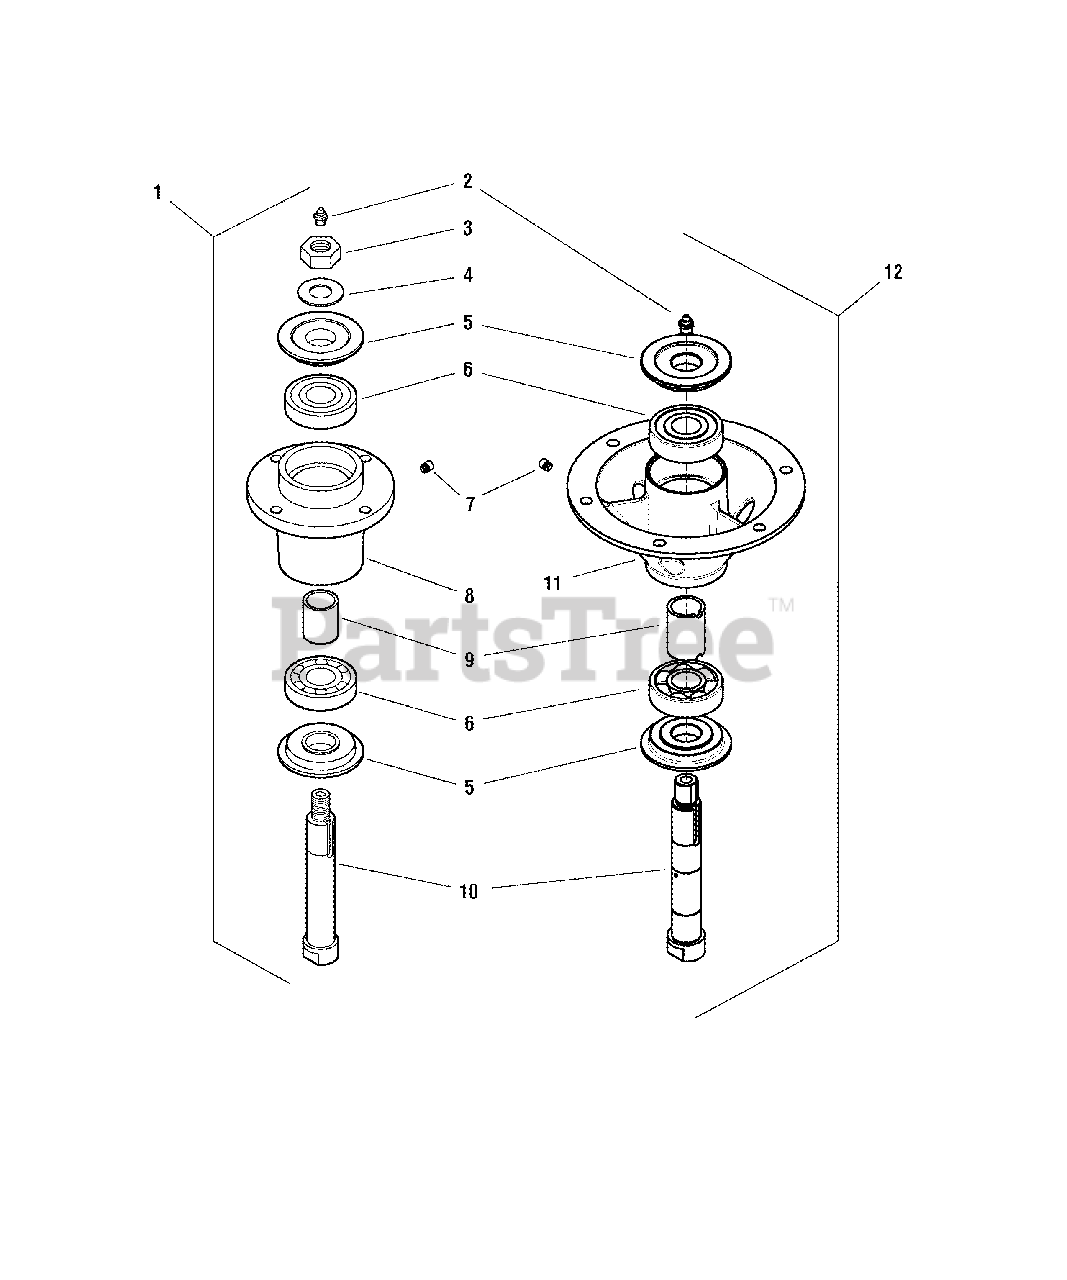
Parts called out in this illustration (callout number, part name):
1	SPINDLE ASSEMBLY, Complete
2	GREASE FITTING
3	NUT, 3/4-16 Hex
4	WASHER, 3/4" Belleville
5	TRASH SHIELD
6	BEARING
7	RELIEF VALVE
8	SPINDLE HOUSING
9	SPACER, 1.00 x 1.25 x 1.75
10	SPINDLE SHAFT
11	HOUSING, SPINDLE, BOTTOM MOUNT
12	SPINDLE ASSEMBLY, CAST IRON, COMPLETE
